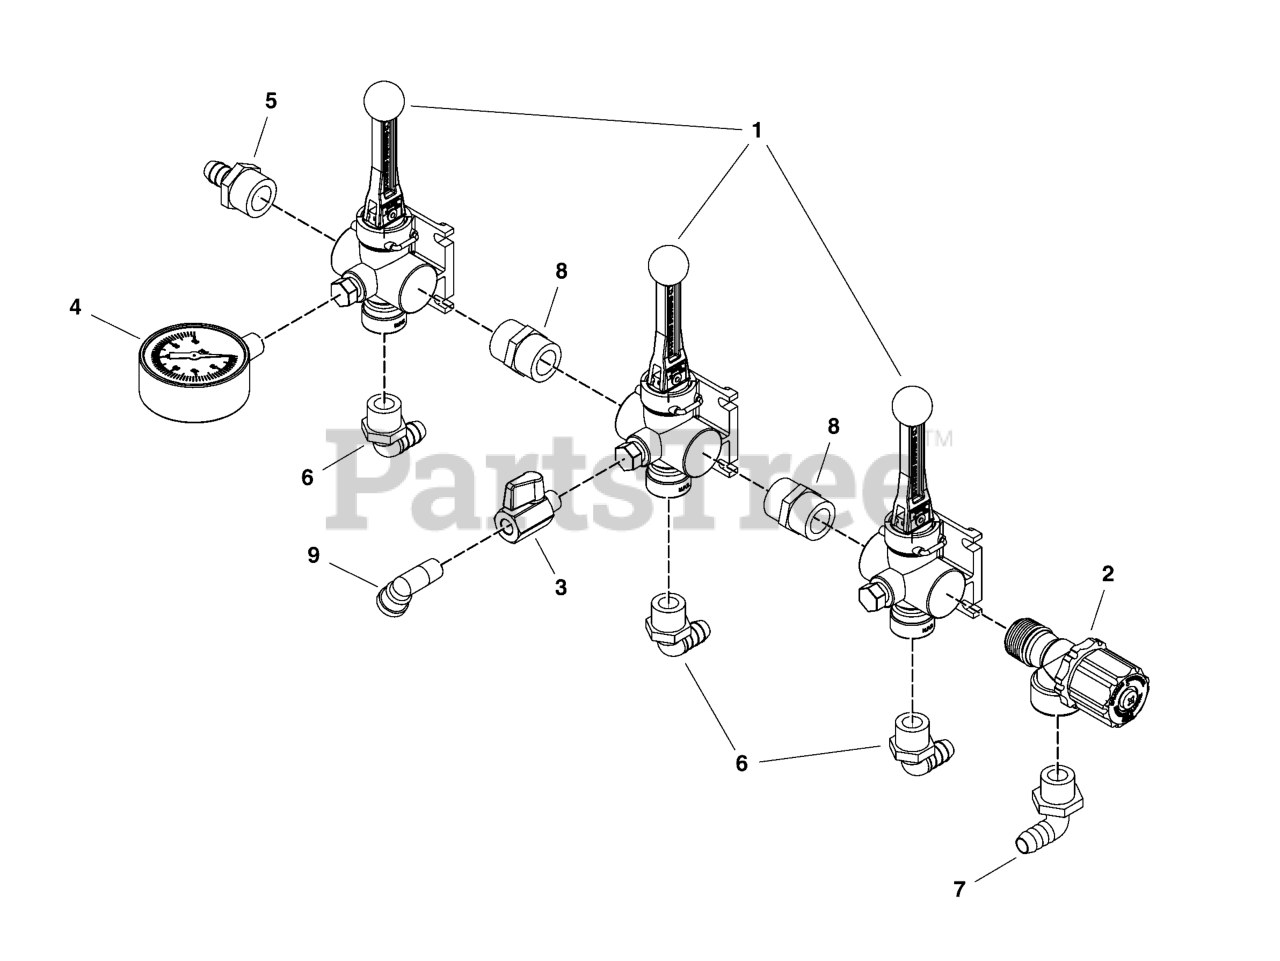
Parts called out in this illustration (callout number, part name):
1	VALVE, DIRECTIONAL FLOW CONTROL, 12 GPM
2	VALVE, PRESSURE RELIEF, SPRAYING SYSTEM
3	VALVE, BALL, 1/4 MPT - 1/4 FPT
4	GAUGE,0-60 PSI, 1/4 NPT, SS GLYC. FILLED
5	FITTING, 3/4 MPT - 1/2 BARB
5	FTG, STR 3/4" MNPT - 1/2" HB BPP
6	FITTING, 1/2 MPT - 1/2 BARB, 90 ELBOW
7	FITTING, 3/4 MPT - 1/2 BARB, 90 ELBOW
8	NIPPLE, 3/4 MPT - 3/4 MPT
9	STREET ELBOW, 1/4 MPT-1/4 FPT, 90 DEG
